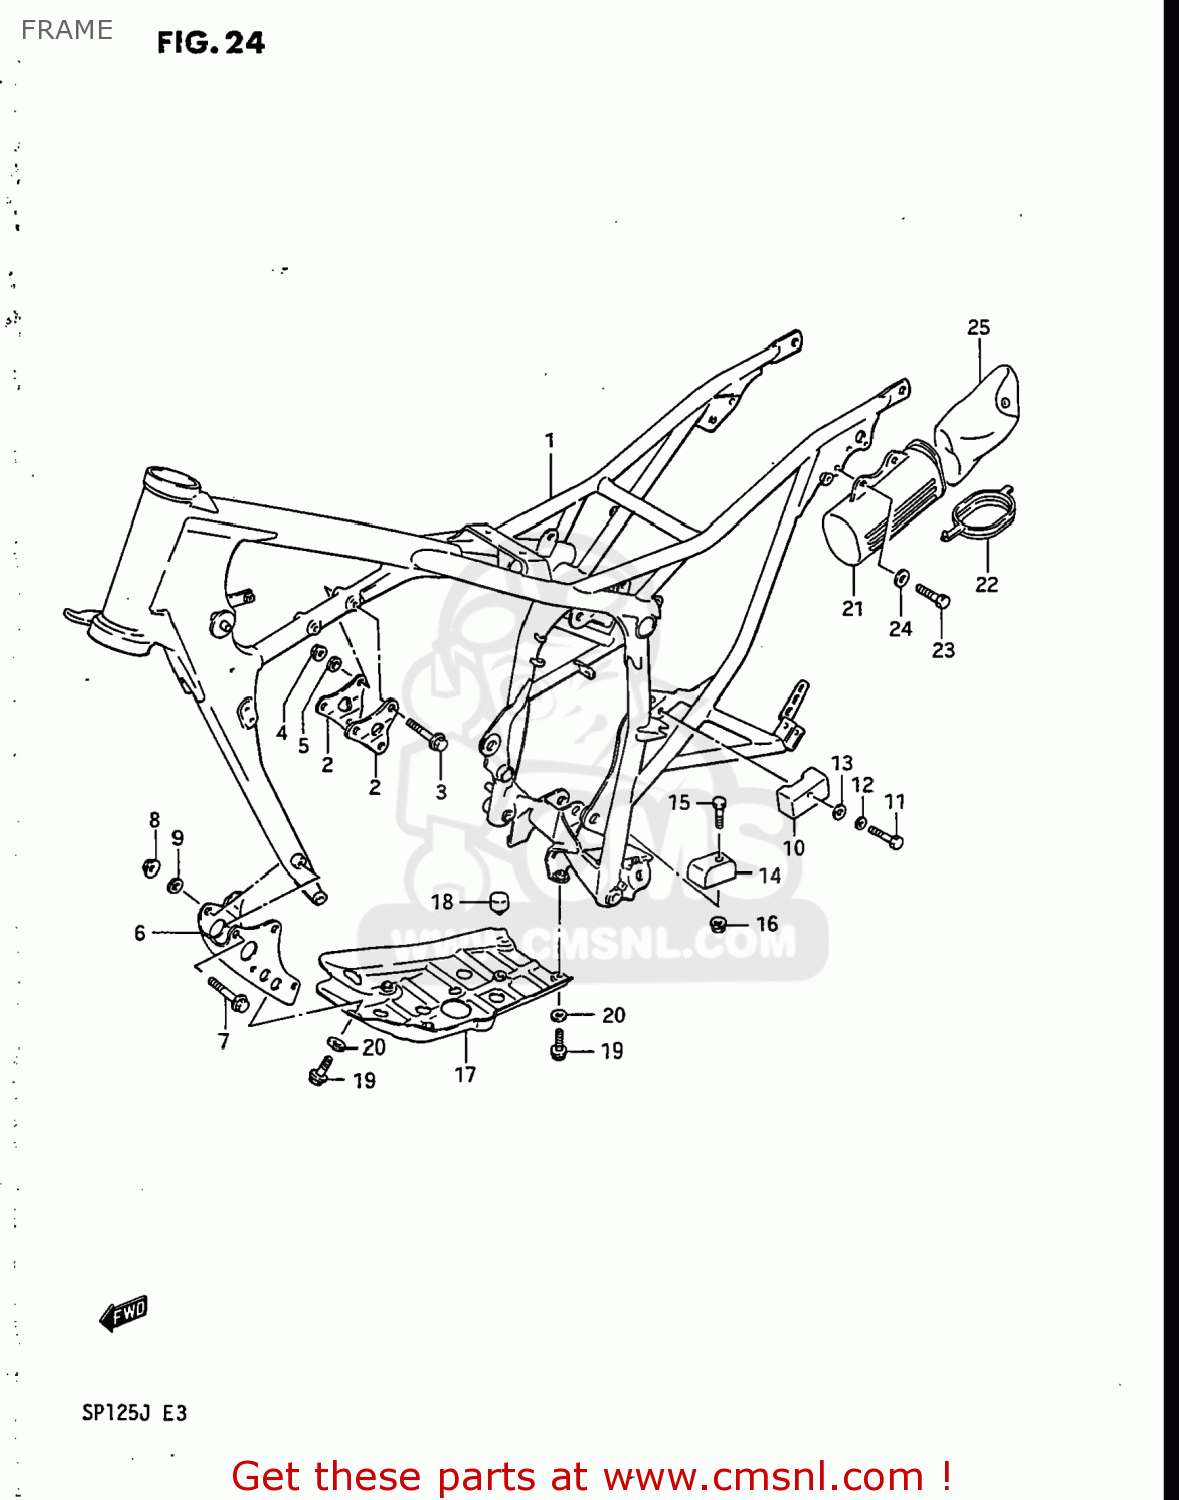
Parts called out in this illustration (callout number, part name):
1	FRAME
2	PLATE,ENGINE MOUNT UPR
3	BOLT
4	NUT
5	LOCK WASHER
6	PLATE,ENGINE MOUNT LWR
7	BOLT 8X70
8	NUT
9	LOCK WASHER
10	GUIDE,CH CONTROL UPR
11	BOLT 6X35
12	WASHER,LOCK
13	WASHER
14	GUIDE,CH LENGTH CONTROL LWR
15	BOLT
16	NUT 6MM
17	PROTECTOR,ENGINE
18	CUSHION
19	BOLT
20	WASHER
21	HOLDER,TOOL
22	CAP,HOLDER
23	BOLT 6X16
24	WASHER (6.5X18X1.6)
25	TOOL SET
